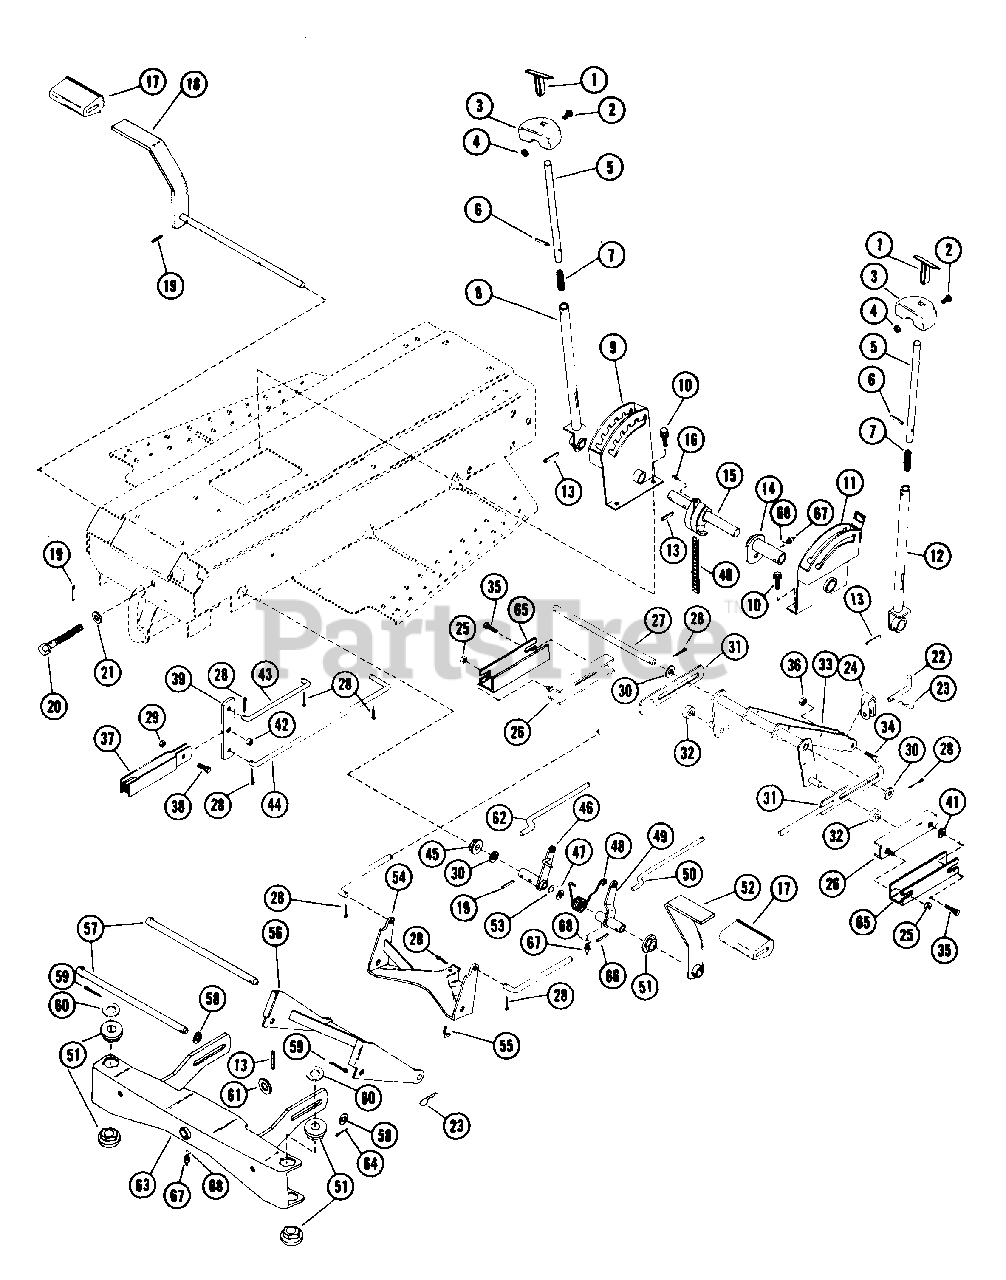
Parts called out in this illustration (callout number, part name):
1	T PLUNGER
2	BLT-HEX 10-24X1.25 FHPL
3	T HANDLE
4	NUT-LK TOP 10-24 PL
6	PIN-ROLL .188X1.50
7	SG-COMP ??X.44X?? WLD 10
8	PAN RAISING HANDLE
9	ATTACHMENT LIFT QUADRANT
10	BLT-SERHFWH .31-18X.50 PL
11	ENGAGEMENT QUADRANT
12	ENGAGEMENT HANDLE
13	PIN-ROLL .250X1.25
14	ENGAGEMENT LEVER
15	MOWER LIFT DRUM
16	PIN-ROLL .156X.88
17	PEDAL COVER
18	BRAKE PEDAL
19	PIN-ROLL .188X1.00
20	CAP SCREW
21	WSHR-FL-STL .505X1.000X.062
22	CLEVIS PIN
23	PIN-HAIR INT .08X.38X1.42 YWZC
24	SWIVEL BLOCK
25	NUT-FLG. .312-18 PL
26	PAN RAIL
27	FLOAT PIN
28	PIN-COTR .12X1.0 PL
29	NUT-LK .312-18 GR A PL
30	WSHR-FL-STL .531X1.062X.095 PL
31	REAR LIFT LINK
33	REAR MOWER HANGER
34	BLT-HEX .38-16X1.75 PL GR2
35	BLT-SERHFWH .31-18X.75 PL
36	NUT-LK-CTR .375-16 GR A PL
37	ADJUSTMENT YOKE
38	BLT-HEX .31-18X.88 PL GR2
39	PIVOT LINK
40	ROLLER CHAIN
41	WSHR-FL-STL .38X.875X.083 PL
42	SPACER BUSHING .5 X .32 X .21
44	MOWER ENGAGEMENT LINK
45	FLANGE BUSHING
46	BRAKE ARM
47	WAVE WASHER .531X.781X.125FH
48	SG-TORS .088X.75X3.0
49	CLUTCH ARM
50	CLUTCH ROD
51	FLANGE BUSHING
52	CLUTCH PEDAL
53	PIN-COTR .06X.50
54	MOWER LIFT LEVER
55	CLEVIS PIN
56	MOWER LIFT ARM
57	HANGER PIN
58	WSHR-FL-STL .505X.880X.072 PL
59	PIN-COTR .12 X 1.25 PL
60	WSHR-FL-STL .755X1.375X.062 PL
61	WSHR-FL-STL .755X1.375X.125 PL
62	BRAKE ROD
63	AXLE
64	PIN-COTR .09X1.0 PL
65	CHANNEL
68	NUT-KEPS 10-24 PL
69	BLT-HEX 10-24X.38 PL GR2
